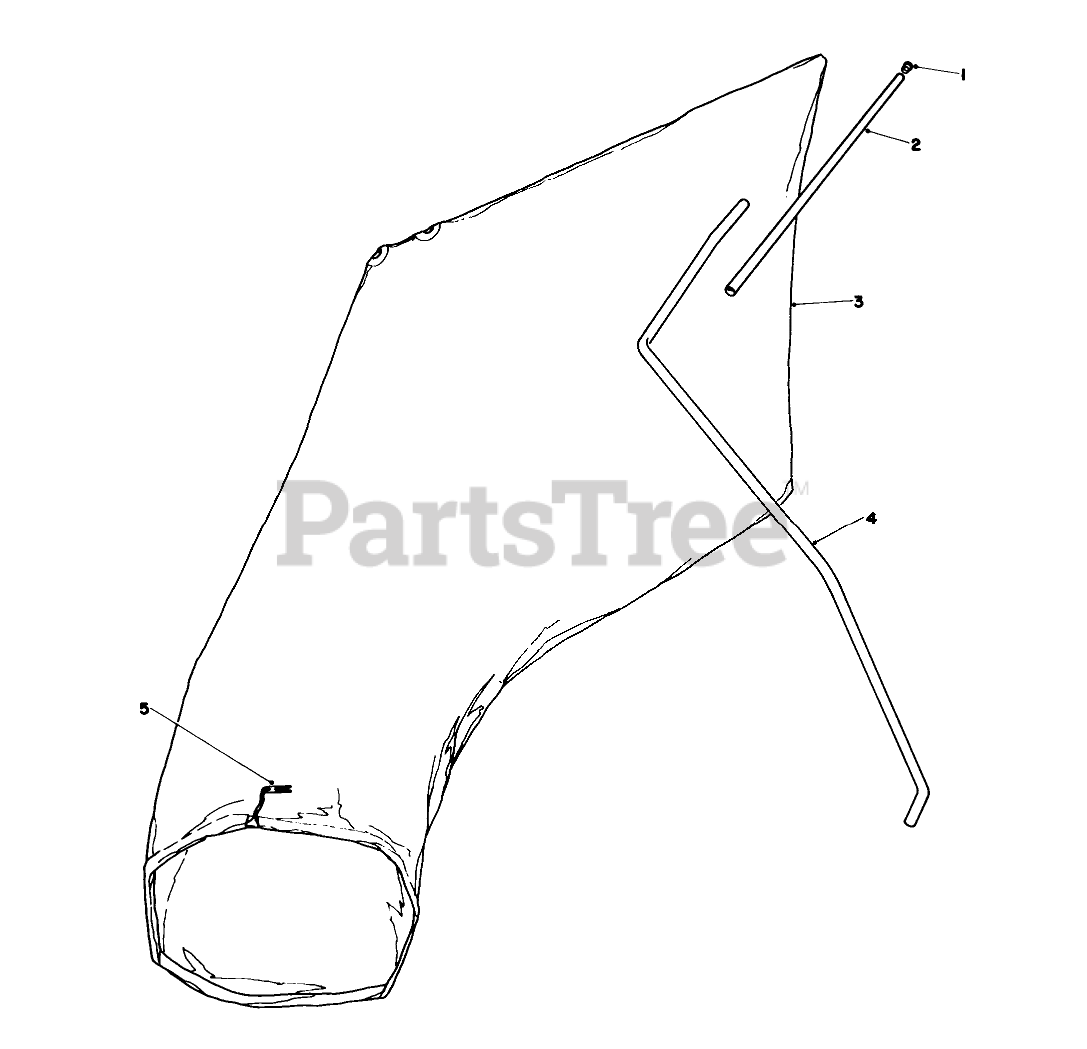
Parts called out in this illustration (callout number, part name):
2	BAG HANGER TUBE
3	Bag (Incl. Ref. #5)
4	HANGER ROD
5	BAG CORD FASTENER
